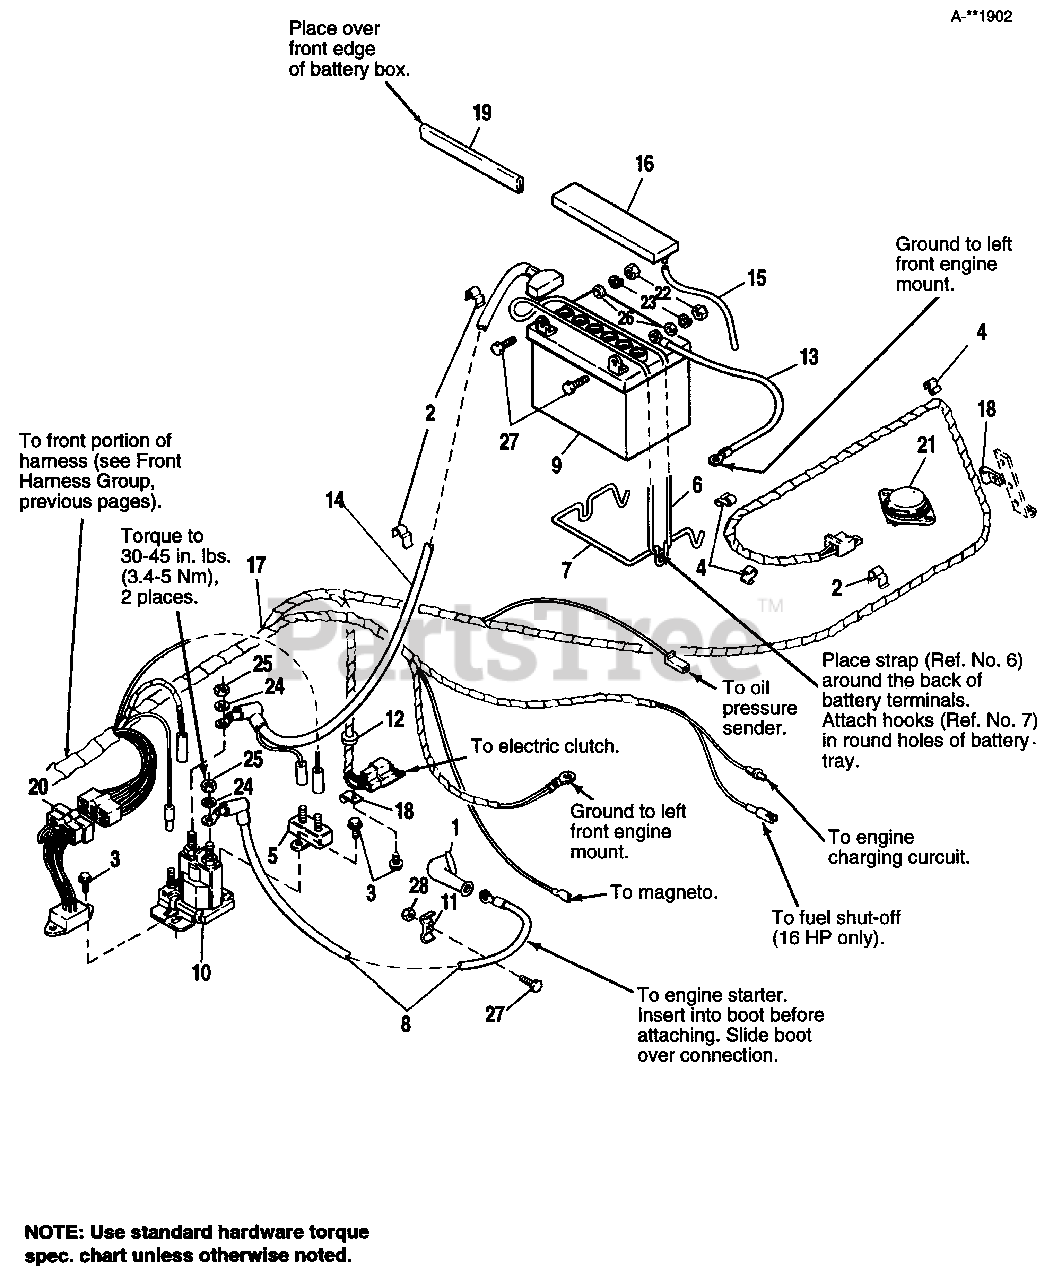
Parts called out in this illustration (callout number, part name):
1	COVER, Terminal
3	SCREW, Taptite, 1/4-20 x 3/4
4	CLIP, Wire
5	CIRCUIT BREAKER
6	STRAP, Battery
7	BRACE, Battery Hold Down
8	CABLE ASSY., Starter
9	BATTERY, 12 Volt
10	SOLENOID
13	CABLE ASSY. (Battery to Ground)
14	CABLE ASSY. (Battery Positive)
15	HOSE, Drain, Battery
16	VENT CAP, Battery
17	WIRING HARNESS
18	CLAMP, Wire
20	MODULE, DSI, Interlock
21	SWITCH, Seat
22	NUT, Hex, 1/4-20
23	LOCKWASHER, 1/4
24	LOCKWASHER, 5/16
25	NUT, Hex, 5/16-24
26	WASHER, 1/4
27	CAPSCREW, Hex, 1/4-20 x 3/4
28	NUT, Hex, Whizlock, 1/4-20
